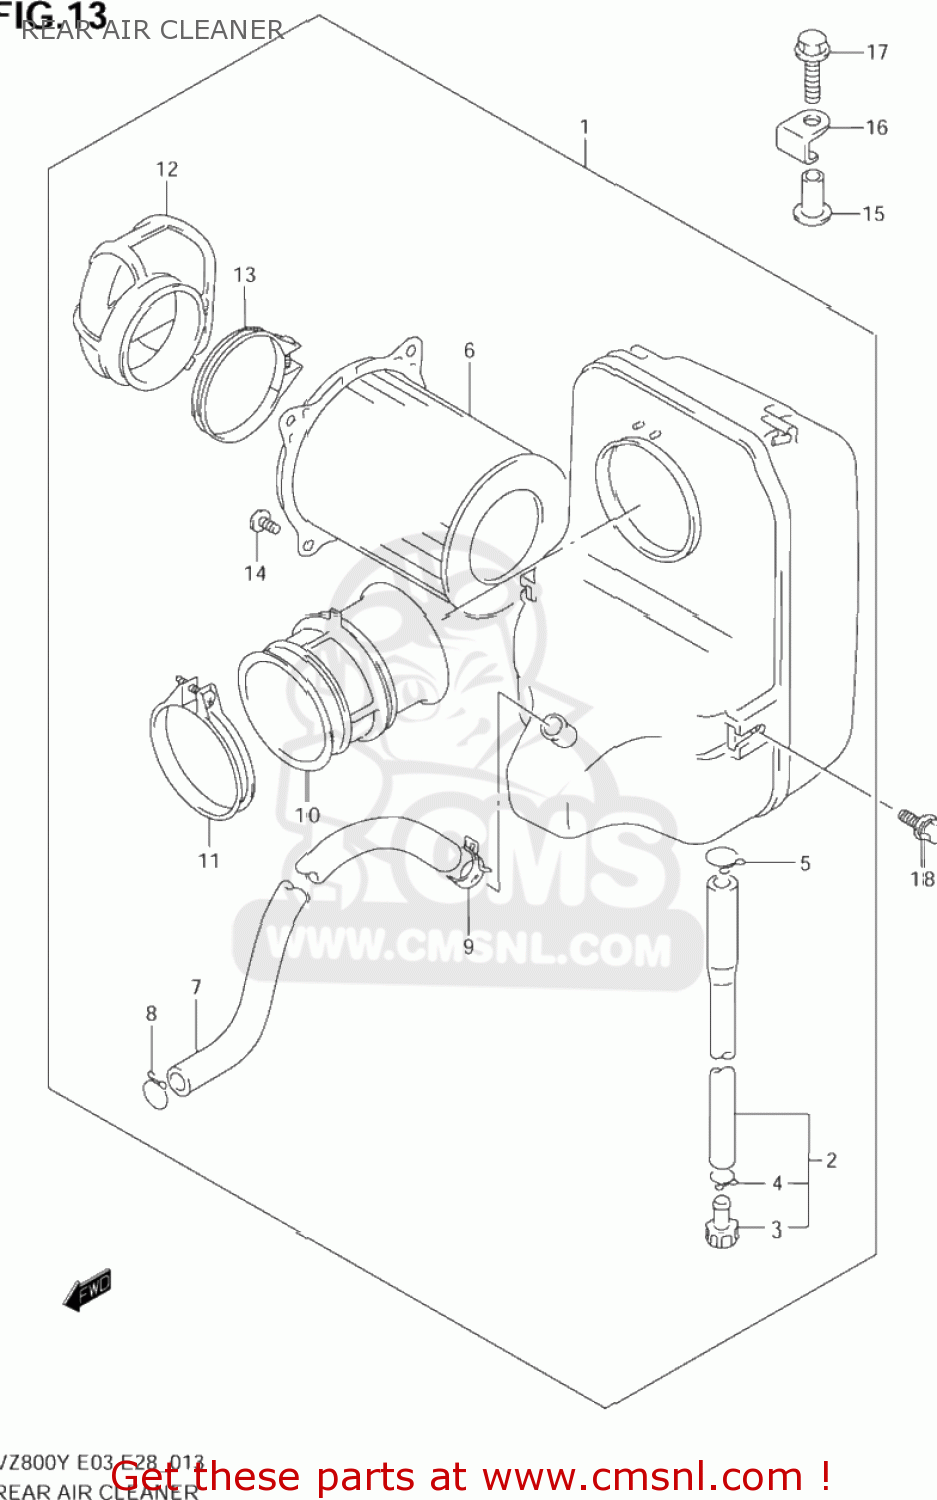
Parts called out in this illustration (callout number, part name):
1	CLEANER ASSY,AIR RR
2	TUBE,DRAIN
3	STOPPER,DRAIN
4	CLIP
5	CLIP
6	FILTER ASSY
7	TUBE,BREATHER
8	CLIP
9	CLIP
10	TUBE,OUTLET
11	CLAMP
12	TUBE,INLET
13	CLAMP
14	SCREW
15	SPACER,AIR CLEANER RR
16	PLATE,AIR CLEANER RR
17	BOLT
18	BOLT
